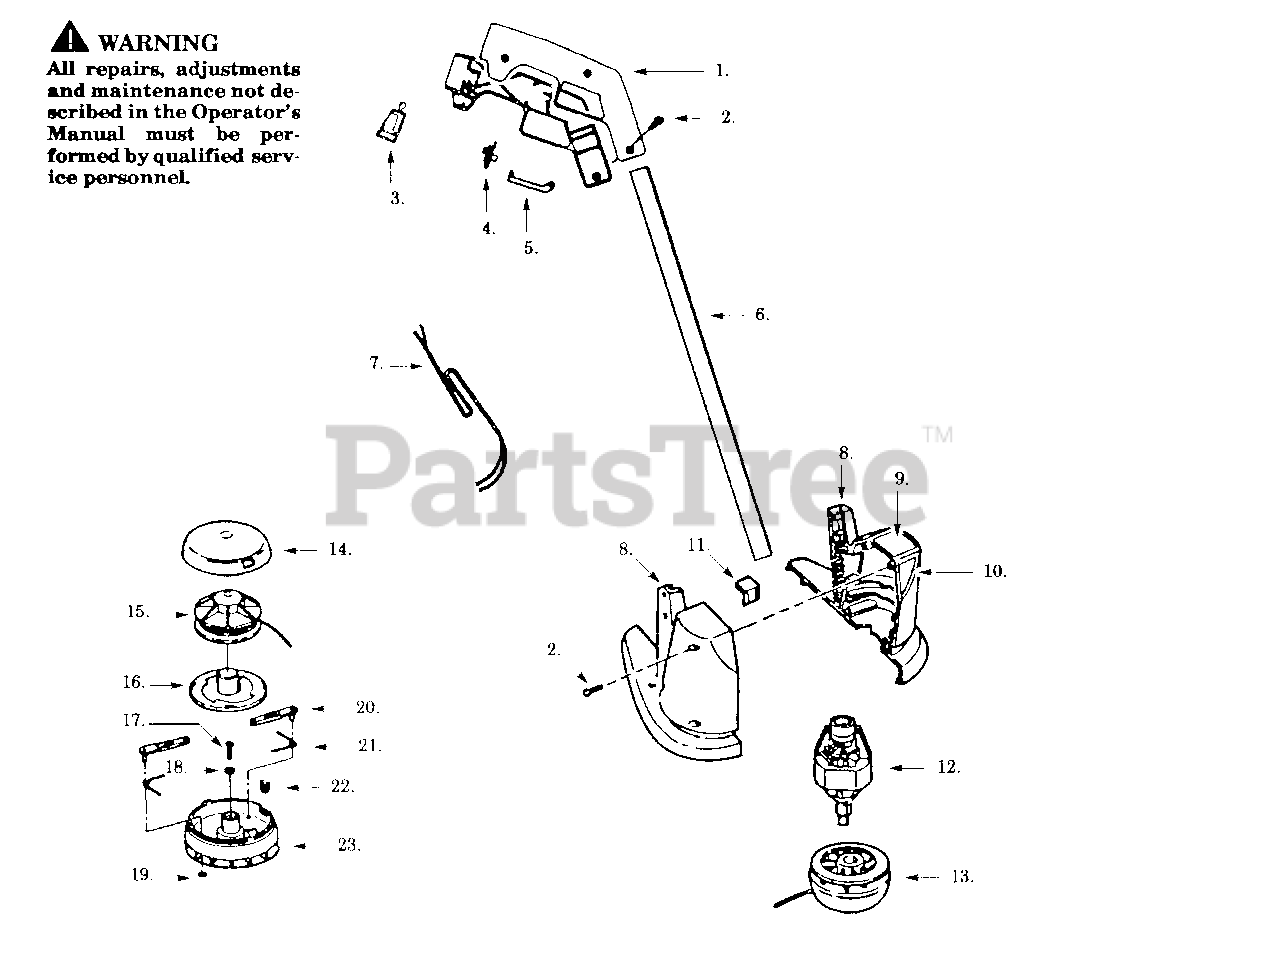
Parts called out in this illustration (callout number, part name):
1	Handle Set
3	Cord Retainer
4	On/Off Switch
5	Trigger Switch
6	Tube Ass'y. w/ Decal
7	Plug/Harness Ass'y.
8	Housing Set
9	Housing Top Label (Not a serviceable part)
10	Hsg. Front Label
11	Blade/Bracket Ass'y.
12	Motor Ass'y.
13	Cutting Head Ass'y.
15	Spool w/Line
19	Push Nut
22	Line Shield
23	Housing Ass'y.
